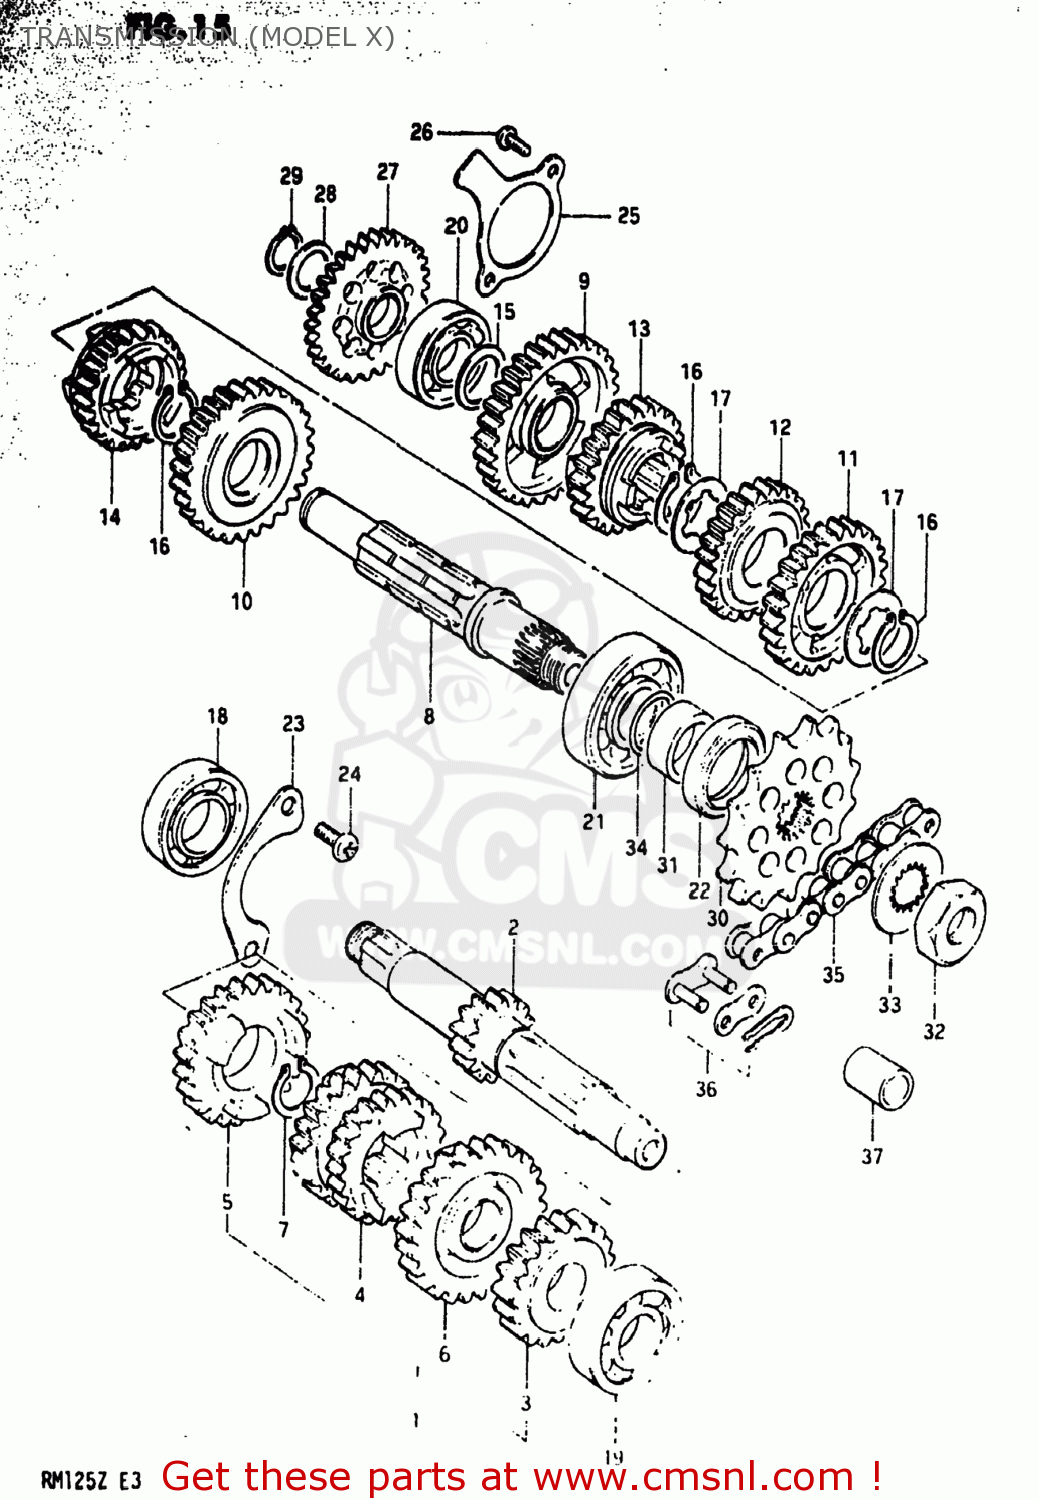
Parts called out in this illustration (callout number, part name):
1	SHAFT,COUNTER
2	SHAFT,COUNTER
3	GEAR,SECOND DRIVE
4	GEAR,THIRD/FOURTH DRIVE
5	GEAR,FIFTH DRIVE
6	GEAR,SIXTH DRIVE
7	CIRCLIP
8	SHAFT,DRIVE
9	GEAR,FIRST DRIVEN
10	GEAR,SECOND DRIVEN
11	GEAR,THIRD DRIVEN
12	GEAR,FOURTH DRIVEN
13	GEAR,FIFTH DRIVEN
14	GEAR,SIXTH DRIVEN
15	WASHER,THRUST
16	CIRCLIP
17	WASHER,LOCK
18	Bearing
19	BEARING
20	BEARING, RH
21	BEARING(20X47X14)
22	SEAL,OIL(25X40X7)
23	RETAINER,CNTR SHAFT BEARING
24	SCREW 6X12
25	RETAINER,DRIVESHAFT
26	SCREW 6X12
27	GEAR,KICK STARTER IDLE
28	WASHER,THRUST
29	CIRCLIP,15MM
30	SPROCKET,ENGINE
31	SPACER(20X25X12.5)
32	NUT
33	WASHER,LOCK
34	O RING(D:1,ID:19.5)
35	CHAIN ASSEMBLY,DRIVE
36	JOINT ASSEMBLY,CHAIN
37	CUSHION
